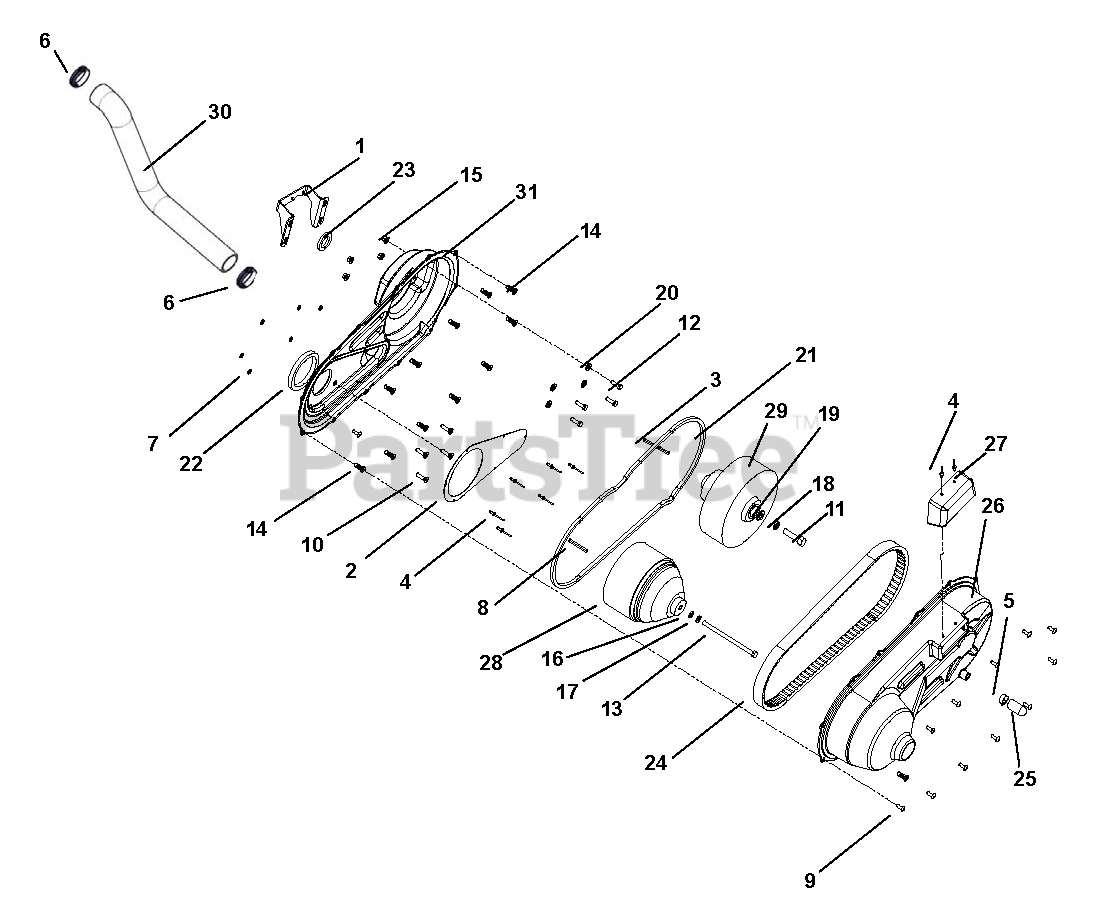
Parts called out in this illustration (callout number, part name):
1	BRACKET, CVT COVER TO TRANS.
2	INLET DUCT, CVT
3	KEY 3/16 X 3
4	RIVET POP 3/16 .126-.250
5	SPRING CLAMP 1" OD HOSE
6	CLAMP,HOSE,WRM DRV,1.81X2.75
7	RIVET POP WASHER 3/16
8	KEY .187 X .247 X 2.25 LG
9	SCR-MCH .25-20X.75 TXTR YWZC
10	BOLT, 5/16-24 X .75 HSFHCS
11	BLT-HEX .50-20X2.0 GR5 YWZC
12	@BLT-HEX .31-18X1.00 GR5 YWZC
13	HHCS 3/8-24X6 1/2 GR5 PLT
14	INSERT, 1/4-20 ARS4-420-280
15	@NUT-LK-TOP-FLG .31-18 YWZC
16	@WSHR-FL-STL.406X.812X.065 YWZ
17	@WSHR-LK .38X.094 REG YWZC
18	@WSHR-LK .50X.125 REG YWZC
19	@WSHR-FL-STL.531X1.06X.095YWZC
20	WASHER FLAT 5/16 NEOPRENE PLT
21	SEAL, MAIN TRUCK CVT HOUSING
22	GASKET, CVT, FOAM
23	SEAL, CVT TO TRANSAXLE
24	BELT, CVT -LP3
25	CAP, DRAIN 7/8 OD PORT
26	ENCLOSURE, CVT OUTER
27	OUTLET DIVERTER, CVT
28	CLUTCH,DRIVER,25MPH
29	DRIVEN, CVTECH POWERBLOC-LP3
30	INTAKE TUBE, CVT ENCLOSURE
31	ENCLOSURE, CVT INNER
